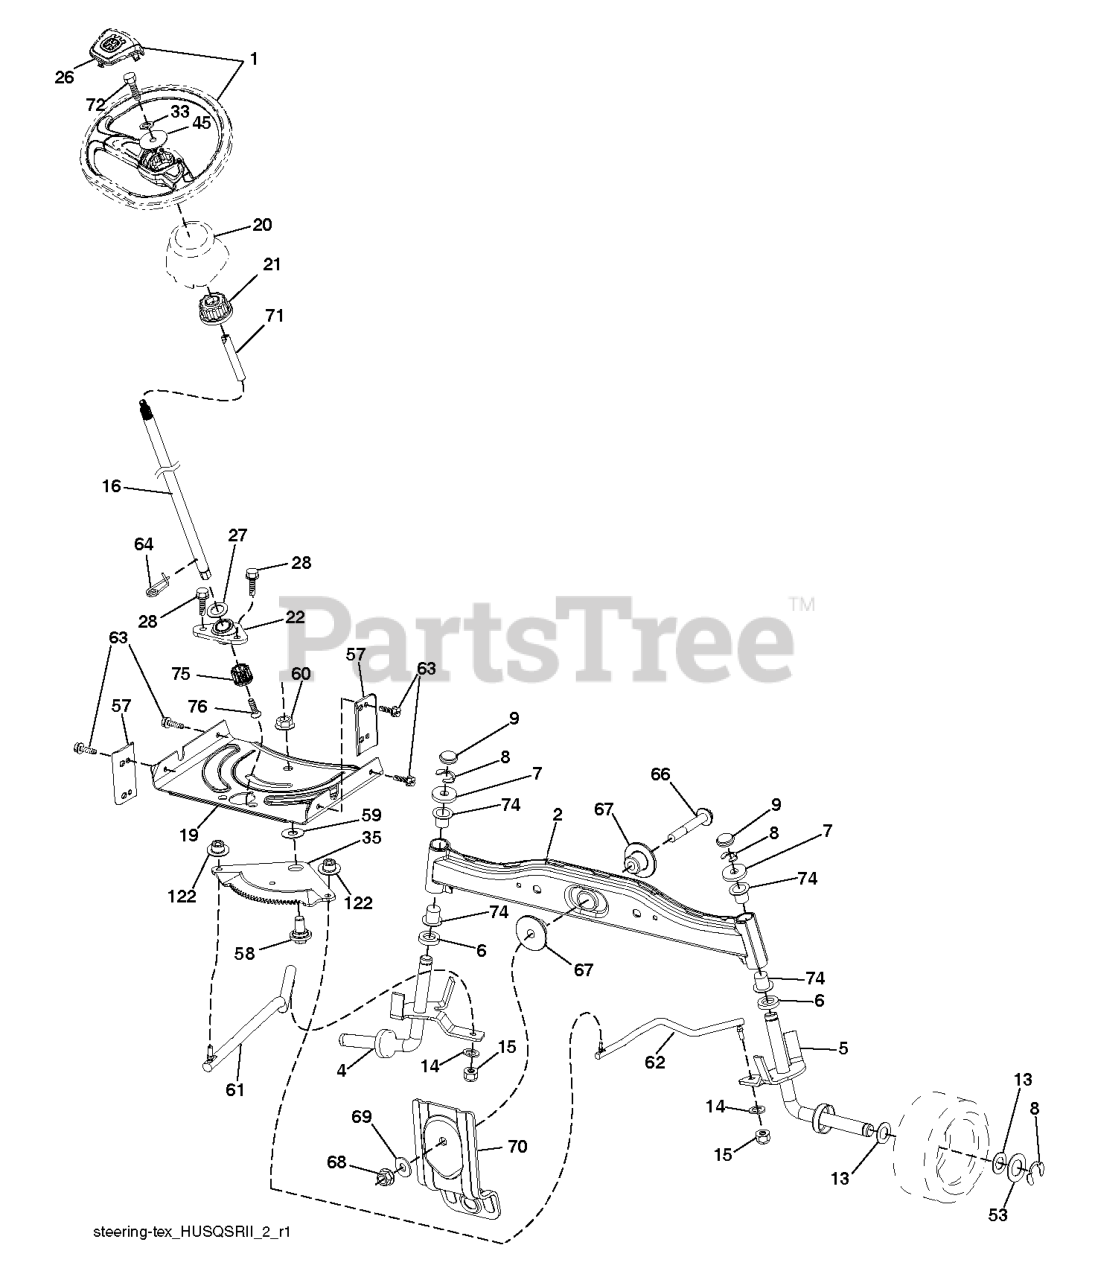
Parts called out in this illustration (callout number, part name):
1	Service Kit
2	SERVICE KIT AXLE HALF ASM
4	SPINDLE.WLDMT.LH.15INTIRE.X431
5	SPINDLE.WLDMT.RH.15INTIRE.X431
6	WASHER THRUST
9	CAP.SPINDLE.BLACK
15	NUT CROWNLOCK 3/8-24
16	KIT.SRVC.STEERINGSHAFT.3HISHFT
19	SERVICE KIT PLATE PLATE.STEER.
20	STEERING.BOOT.HUSQ.LT
21	KIT.SRVC.STEERINGSHAFT.ADAPTER
22	KIT.SRVC.STEERINGSHAFT.LWRBSHG
28	SCREW, 3/8-16X3/4
33	WASHER SPRING LOCK WASHER WITH
35	GEAR.SECTOR.PLATE.DDL.
53	WASHER.HARDENED
57	BRACKET.UPSTOP.TEX
58	BOLT.SHOULDER.SECTOR.P
59	WASHER.THURST.SECTOR.S
60	NUT.FLANGE.LOCK.5/8-11
63	BOLT.HEX.HD.WASHER.5/16-18X.75
64	RETAINER.CLIP.SPRING.S
66	BOLT HEX FGHD 7/16-14 X 3 SERR
68	NUT.LOCK.FLANGE.7/16
69	WASHER.1.5X.505X.118
70	BRACKET FRONT DECK SUSPENSION
71	SHAFT.EXTEN.STRG.SPLINE
74	BEARING.STEERING.COLUMN
75	KIT.SRVC.STEERINGSHAFT.PINION
76	SCREW HEAD SOCKET LRVB
122	CAP.GEAR.SECTOR.TEX
